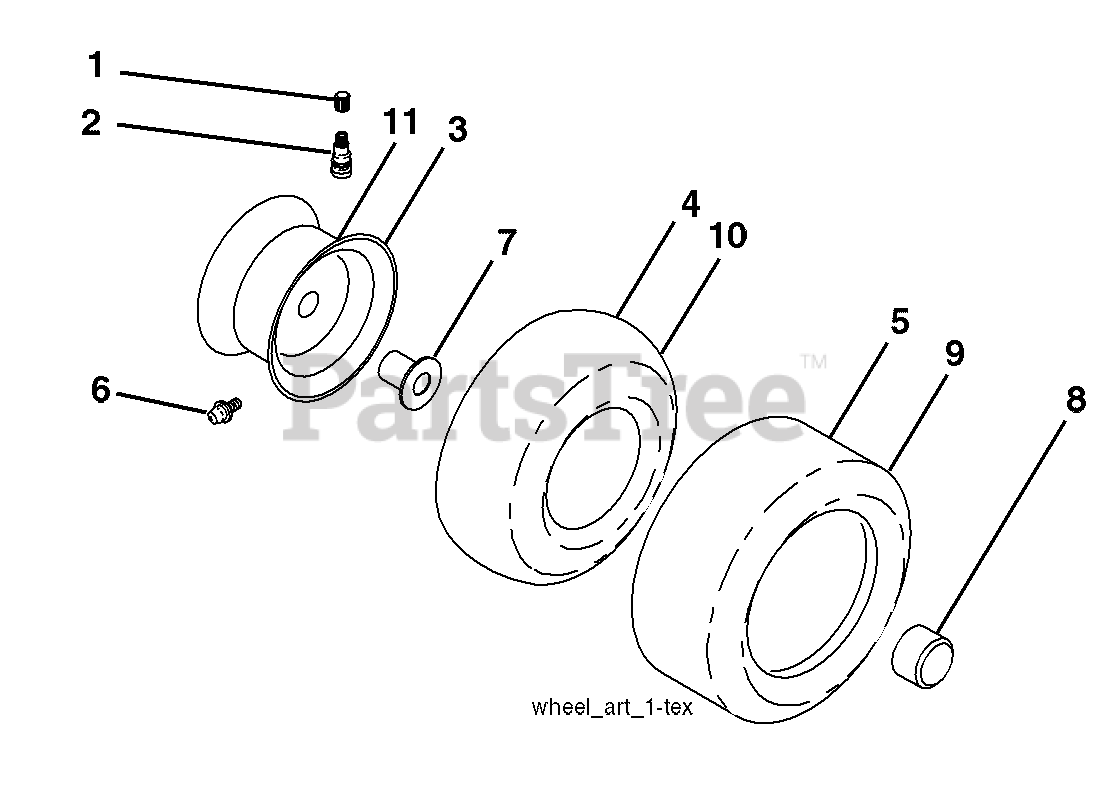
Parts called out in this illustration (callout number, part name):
1	Cap Valve Tire
2	Stem Valve
3	Rim Asm 6" Front Service
4	Tube Front
5	Tire FT 15 x 6 0 - 6 Service
6	Fitting Grease
7	Bearing Flange
8	Cap Axle Blk 1 50 x 1 00
9	Tire R T 18 x 9.5-8 Service
10	Tube Rear
11	Rim Asm 8" rear Service
11	Sealant, Tire
